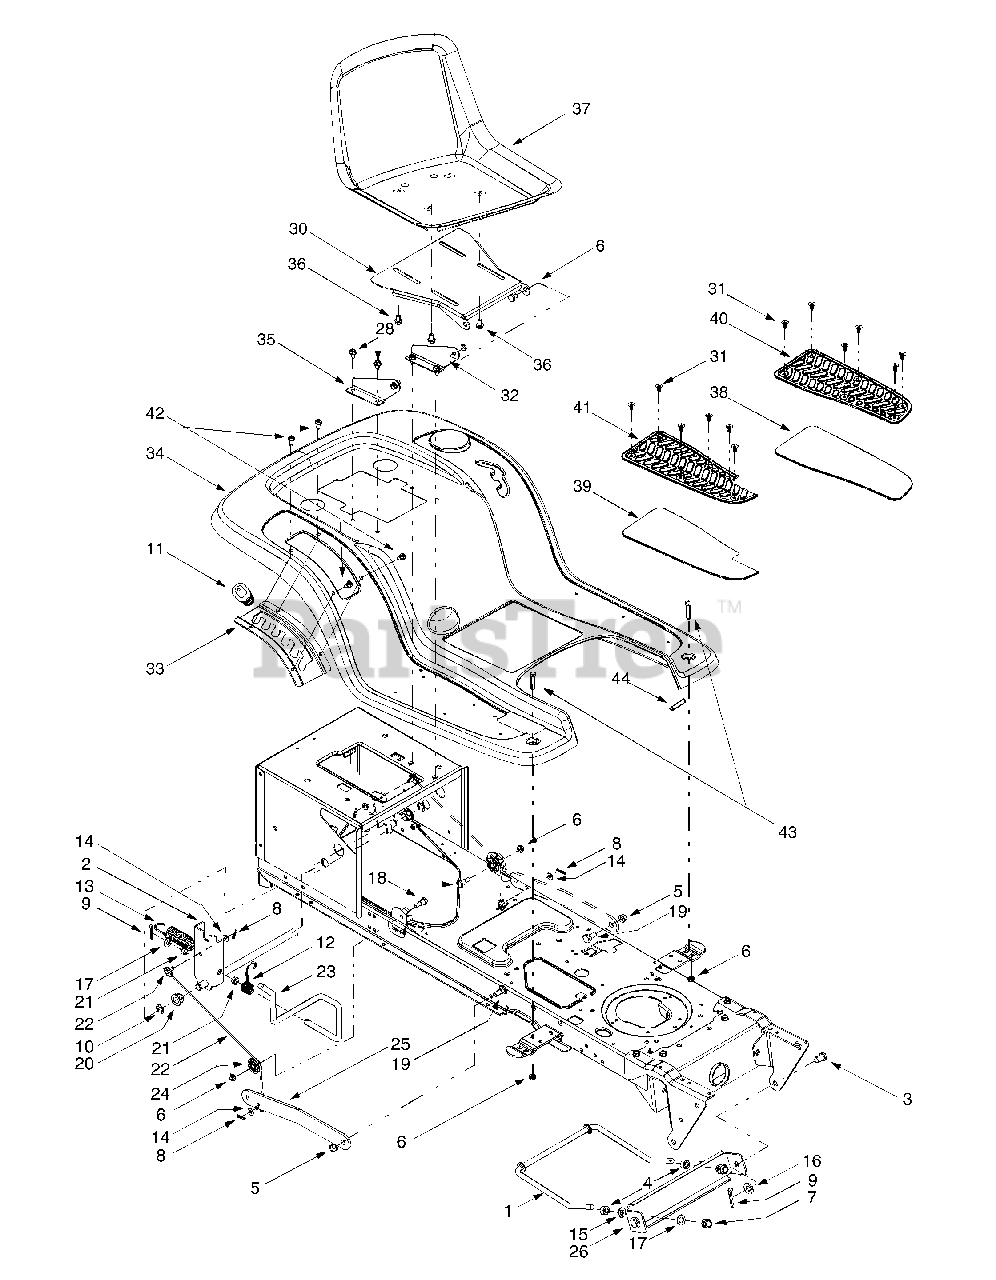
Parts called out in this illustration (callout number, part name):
3	Clevis Pin, .5 x .78
5	Flange Lock Nut, 3/8-16
6	Flange Lock Nut, 5/16-18
7	Hex Nut, 1/2-13
8	Internal Cotter Pin
9	Cotter Pin
10	E-ring
11	Handle Grip
12	Torsion Spring
13	Lift-assist Spring, 1.15 x 5.99
14	Flat Washer, 5/16
15	Lock Washer, 1/2
16	Flat Washer, .31 x 1.062 x .134
17	Flat Washer, .51 x 1.12 x .06
18	Hex Cap Screw, 5/16-18 x .62
19	Shoulder Screw, .5 x .27, 3/8-16
20	Hex Flange Bearing
21	Snap Flange Bearing
22	Lift Cable, 16.16
23	Lift Handle
24	Roller Pulley
28	Self-tapping Screw, 5/16-18 x .625
32	Shoulder Screw, .437 x 1.62
36	Hex Washer Head Screw, 3/8-16 x .625
37	Seat, Medium Back
38	LH Abrasive Foot Pad
39	RH Abrasive Foot Pad
40	LH Rubber Foot Pad
41	RH Rubber Foot Pad
42	Self-tapping Screw, 5/16-18 x .75
43	Hex Cap Screw, 5/16-18 x .62
44	Trim Strip, 1.5
